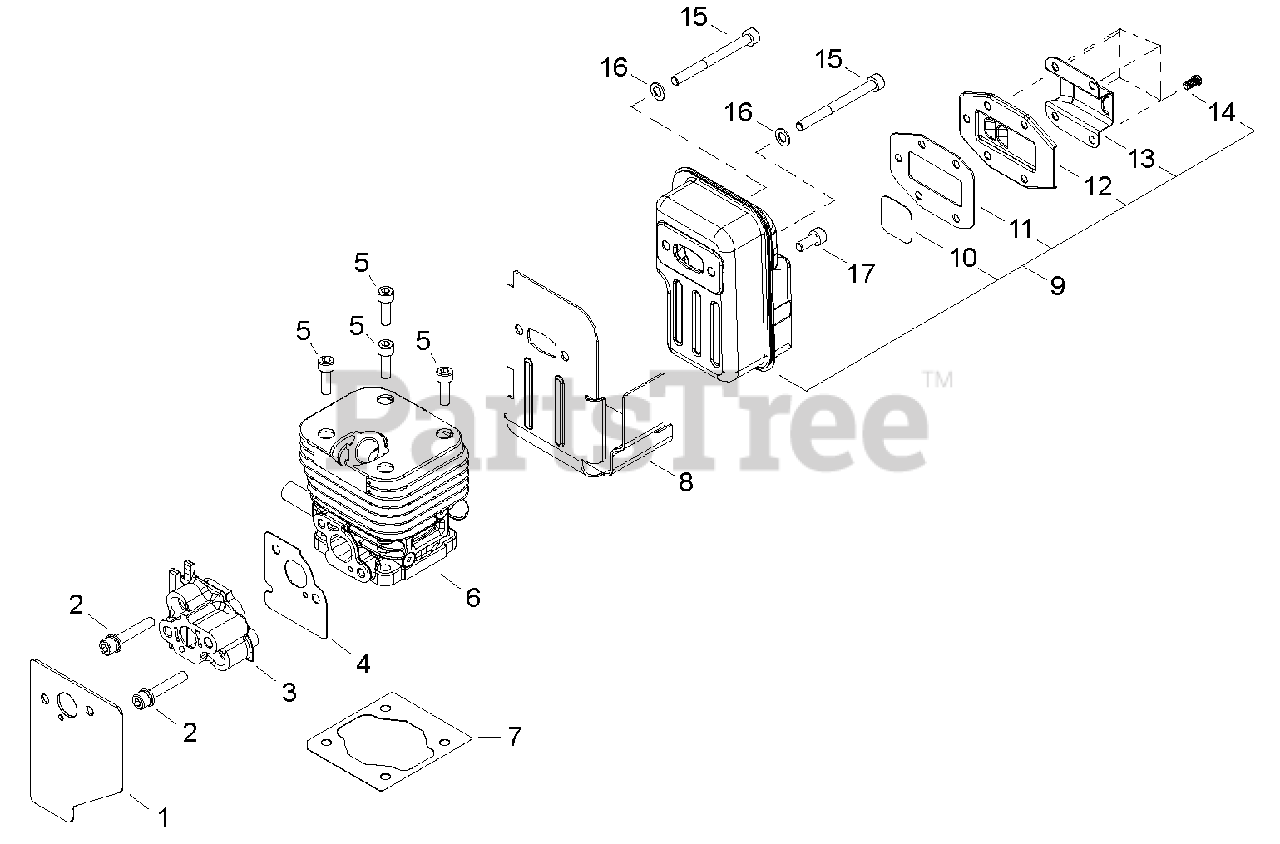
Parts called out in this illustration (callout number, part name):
1	GASKET, CARBURETOR
2	BOLT M5×30
3	INSULATOR
4	HEAT SHIELD, INTAKE
5	BOLT 5×16
6	CYLINDER ASSY
7	GASKET, CYLINDER
8	HEAT SHIELD, EXHAUST
9	MUFFLER ASSY
10	SCREEN, SPARK ARRESTER
11	GASKET, EXHAUST
12	COVER, SPARK ARRESTER
13	OUTLET, EXHAUST
14	SCREW M4×8
15	BOLT M5×55
16	WASHER SS 5 MM
17	BOLT 5×12
